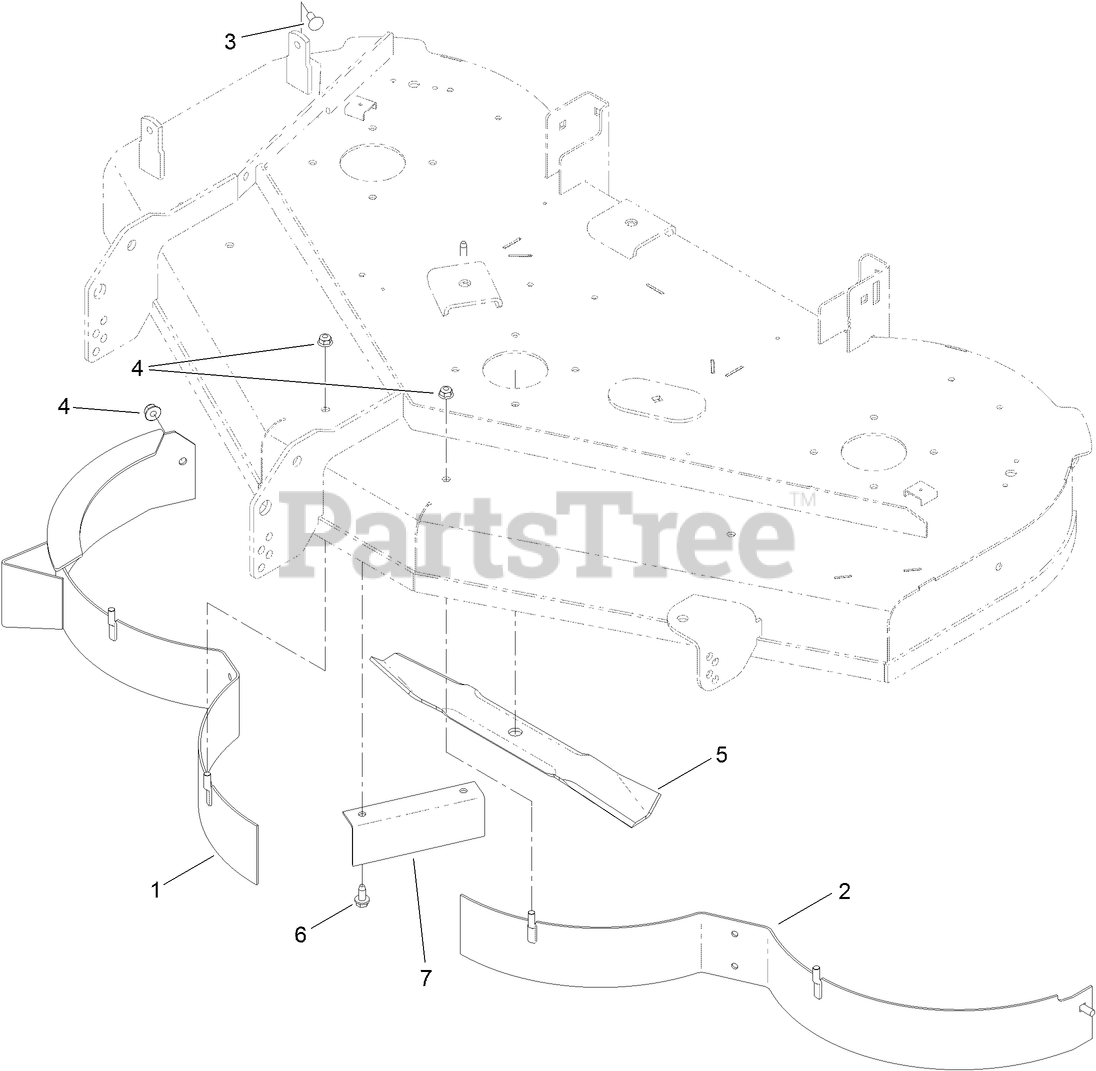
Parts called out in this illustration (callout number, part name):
1	BAFFLE-RH
2	BAFFLE-LH
3	BOLT-CARR
4	NUT-HF, NI
5	BLADE-MULCH, 17.50 INCH
6	SCREW-HWHTF
7	BRACKET-RECYCLER
